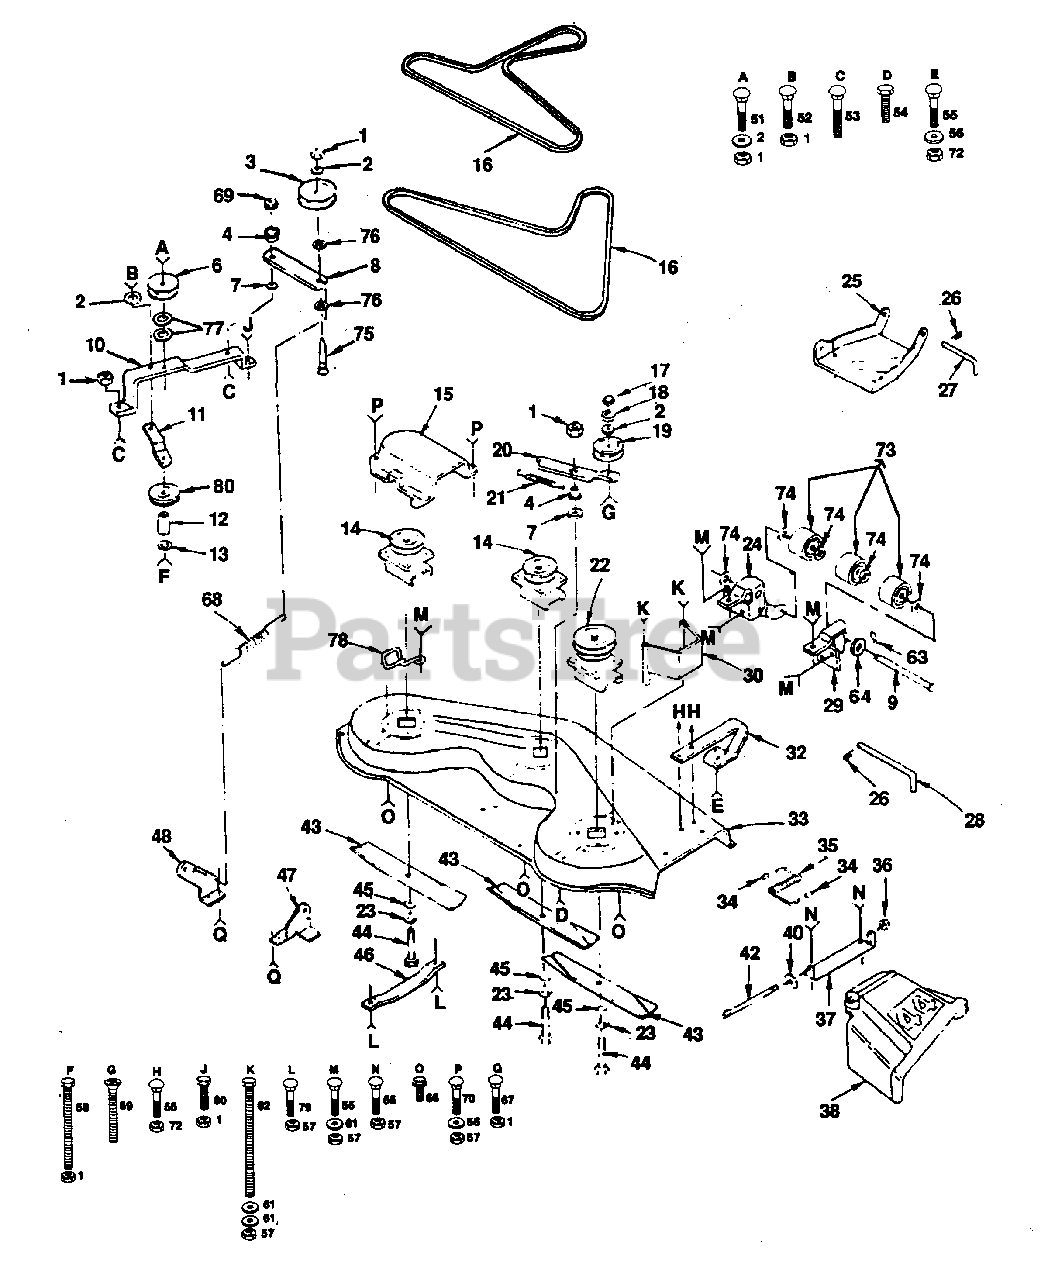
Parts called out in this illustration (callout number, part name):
1	Locknut 3/8 x 16
2	Washer 13/32 x 1 x 14 Ga. (AYP part number)
3	Pulley, Idler (AYP part number)
4	Spacer (AYP part number)
6	Pulley, Idler (AYP part number)
7	Washer, Wear (AYP part number)
8	Arm, Idler (AYP part number)
9	Pin, Pivot (AYP part number)
10	Bar, Support, Idler (AYP part number)
11	Brace, Idler, Deck (AYP part number)
12	Spacer (AYP part number)
13	Washer 13/32 x 13/16 x 16 Ga. (AYP part number)
14	Mandrel, Secondary (AYP part number)
15	Guard (AYP part number)
16	V-Belt (AYP part number)
17	Nut, Hex 3/8 x 16 (AYP part number)
18	Washer, Lock 3/8 (AYP part number)
19	Idler, Flat (AYP part number)
20	Arm, Idler, Deck (AYP part number)
21	Spring, Extension (AYP part number)
22	Mandrel, Primary (AYP part number)
23	Washer, Lock, Hvy. Helical (AYP part number)
24	Bracket, Lift, LH (AYP part number)
25	Link, Parallel (AYP part number)
26	Retainer, Spring (AYP part number)
27	Pin, Front, Hinge (AYP part number)
28	Pin, Rear, Hinge (AYP part number)
29	Bracket, Lift, RH (AYP part number)
30	Guard, Belt, RH (AYP part number)
32	Runner, RH (AYP part number)
33	Housing, Mower (AYP part number)
34	Cap, Sleeve (AYP part number)
35	Spring (AYP part number)
36	Nut, Push (AYP part number)
37	Bracket, Deflector (AYP part number)
38	Guard, Discharge (AYP part number)
40	Washer 11/32 x 5/8 x 16 Ga. (AYP part number)
42	Rod, Hinge (AYP part number)
43	Blade (AYP part number)
44	Bolt, Hex 3/8 -24 x 1 1/2 Gr.5 (AYP part number)
45	Washer 13/32 x 1 1/4 x 12 Ga. (AYP part number)
46	Runner, LH (AYP part number)
47	Bracket, Suspension, Rear, RH (AYP part number)
48	Bracket, Suspension, Rear, LH (AYP part number)
51	Bolt, Carriage 3/8-16 x 1-3/4 (AYP part number)
52	Bolt, Carriage 3/8-16 x 1 (AYP part number)
53	Bolt, Carriage 3/8-16 x 1 1/2 (AYP part number)
54	Bolt, Hex 3/8-16 x 1-1/4 (AYP part number)
55	Bolt, Carriage 5/16-18 x 3/4
56	Washer 11/32 x 11/16 x 16 Ga. (AYP part number)
57	Locknut 5/16-18
58	Bolt, Hex 3/8-16 x 3 (AYP part number)
59	Screw, Flat Head 3/8-16 x 2 (AYP part number)
60	Bolt, Fin. Hex 3/8-16 X 1 (AYP part number)
61	Washer 11/32 x 3/4 x 16 Ga. (AYP part number)
62	Bolt, Hex 5/16-18 x 5 (AYP part number)
63	Pin, Cotter (AYP part number)
64	Washer, 15/32 X 1X 16 Ga. (AYP part number)
66	Screw, Hex Washer Thread Rolling 3/8-16 x 3/4 (AYP part number)
67	Bolt, Carriage 3/8-16 x 3/4 (AYP part number)
68	Spring, Extension (AYP part number)
69	Nut. Centerlock 3/8-16 (AYP part number)
70	Bolt, Carriage 5/16-18 x 3/4 (AYP part number)
72	Locknut 5/16-18 (AYP part number)
73	Roller, Nose (AYP part number)
74	Washer 15/32 x 1 x 10 Ga. (AYP part number)
75	Bolt, Carriage 3/8-16 x 2-1/2 (AYP part number)
76	Washer 13/32 x 3/4 x 10 Ga. (AYP part number)
77	Washer 13/32 x 7/8 x 10 Ga. (AYP part number)
78	Keeper, L.H. Mandrel (AYP part number)
79	Bolt, Carriage 5/16-18 x 5/8 (AYP part number)
80	Idler, Pulley (AYP part number)
